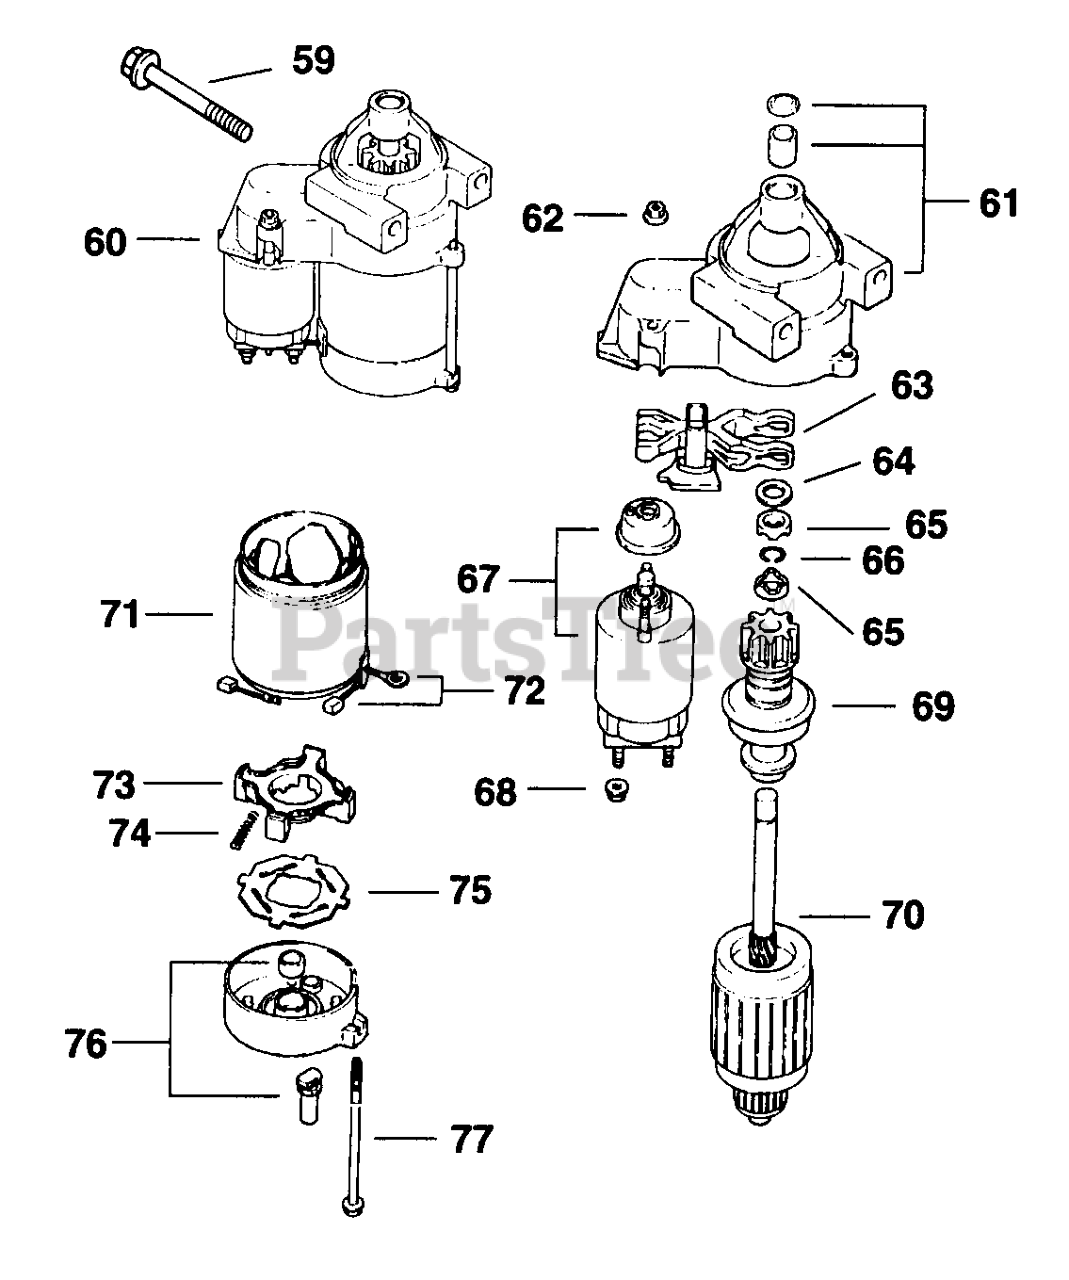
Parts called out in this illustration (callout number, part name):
61	Cap, Drive End
62	Nut, Starter
63	Lever, Starter Drive
64	Washer, Thrust
65	Nut, Stop Collar
66	Ring, Retainer
67	Solenoid
68	Nut, Starter
69	Drive Pinion
70	Armature, Starter Assembly
72	Kit, Brush
73	Holder, Brush
74	Spring, Brush
75	Insulator
76	Cap, Commutator End
77	Bolt, Thru M5x0.8x99
